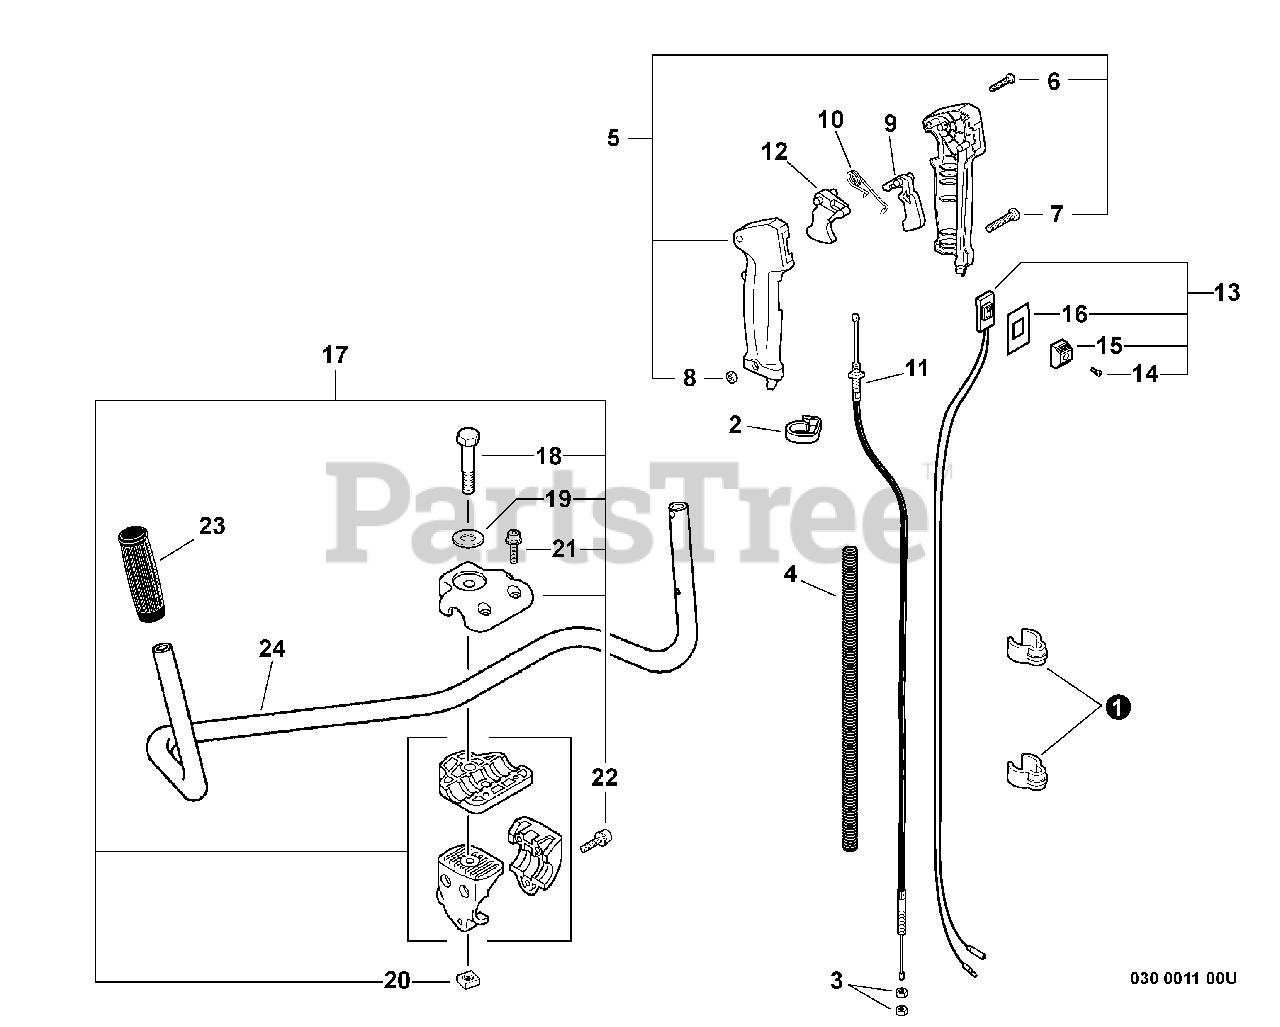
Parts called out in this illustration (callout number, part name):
4	TUBE, PROTECTIVE - CORRUGATED
5	THROTTLE CONTROL ASSY
6	SCREW - 3X25
7	SCREW - 5X30
9	LOCKOUT, THROTTLE
10	SPRING, LOCKOUT LEVER
11	CABLE, THROTTLE
12	TRIGGER, THROTTLE
13	IGNITION SWITCH ASSY
14	SCREW - 3X10
15	KNOB, SWITCH - ORANGE
16	COVER, SWITCH - STOP
17	HANDLE BRACKET KIT
18	BOLT - 8X55
19	WASHER - 8
21	SCREW - 5X20
22	SCREW - 5X30
23	GRIP, HANDLE - LEFT
24	HANDLE - FRONT
